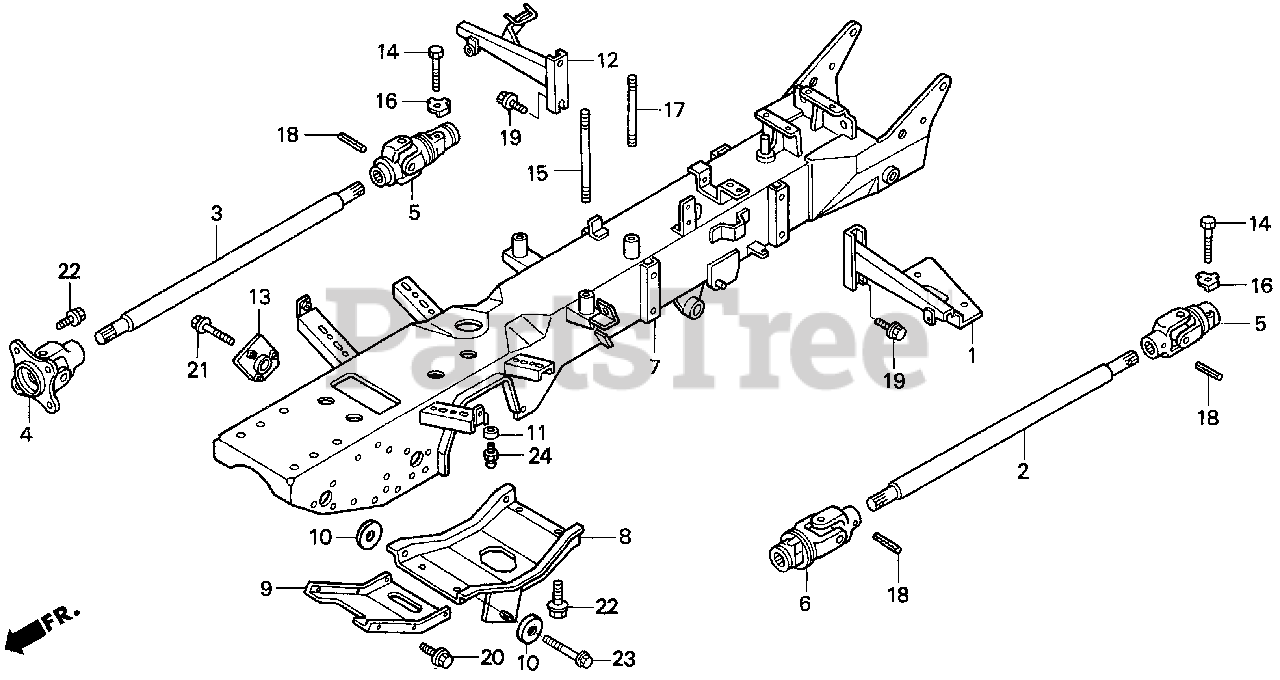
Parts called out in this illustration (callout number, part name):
1	BRACKET A, FUEL TANK
2	SHAFT, PROPELLER (B)
3	SHAFT A, PROPELLER
4	JOINT, UNIVERSAL
5	JOINT E, UNIVERSAL
6	JOINT F, UNIVERSAL
8	COVER A, FRAME (LOWER)
9	COVER B, FRAME (LOWER)
10	COLLAR, FR. ENGINE HANGER (A)
11	COLLAR (6.5X11X3)
12	BRACKET, OIL TANK
13	PIVOT, LIFT LINK
14	BOLT, SPECIAL (8MM)
15	BOLT, STUD (10X128)
16	WASHER, LOCK (8MM)
17	BOLT, STUD (10X90)
18	PIN, SPRING (6X32)
19	BOLT, FLANGE (8X14)
20	BOLT, FLANGE (8X16)
21	BOLT, FLANGE (8X20)
22	BOLT, FLANGE (10X20)
23	BOLT, FLANGE (10X28)
24	FITTING, GREASE (A.76)
